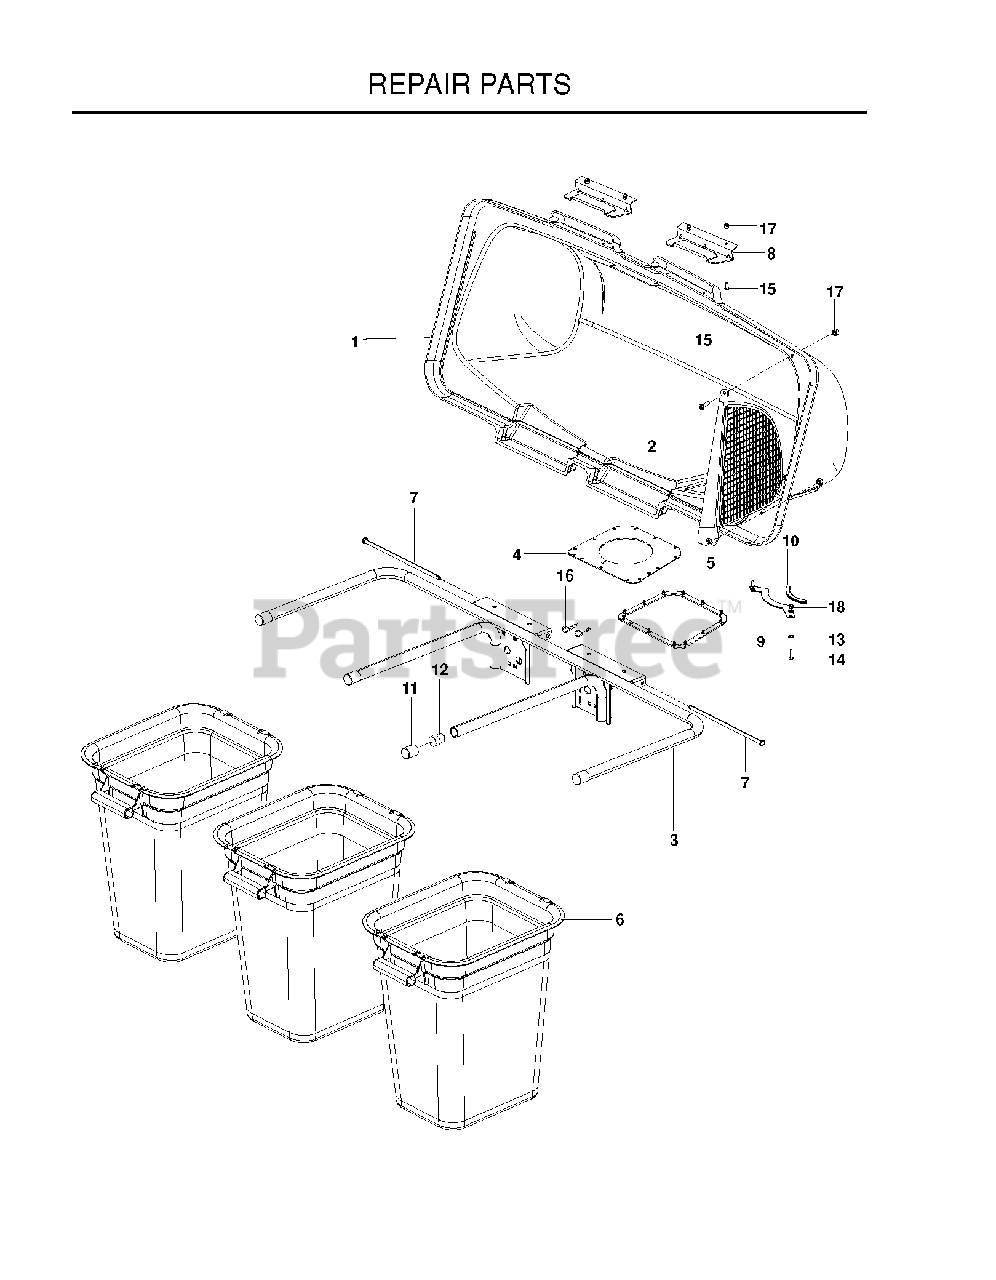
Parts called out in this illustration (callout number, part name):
1	COVER.ASM.3BIN.GENERIC.
2	SCREEN.COVER.BAGGER
3	BAGGER.ASM.FRAME.3BIN.BLACK
4	SEAL.BAGGER.TOP.3-BIN.BLK
5	GASKET.COVER.BAGGER
6	CONTAINER BAG, SOFT
7	BAGGER.HINGE.PIN
8	LATCH CER38
9	Collection Chute Support, Black
10	Flex Trim, 1' Black
11	TUBING PLUG
12	SPACER PLUG, BAGGER
13	FLAT WASHER 5/16 SAE
14	HCS 5/16C X 1 1/4
15	SCREW #10-24 X 5/8
16	RETAINER SPRING
17	NUT 10-24 NYLOC
18	NUT 5/16 NYLOC
